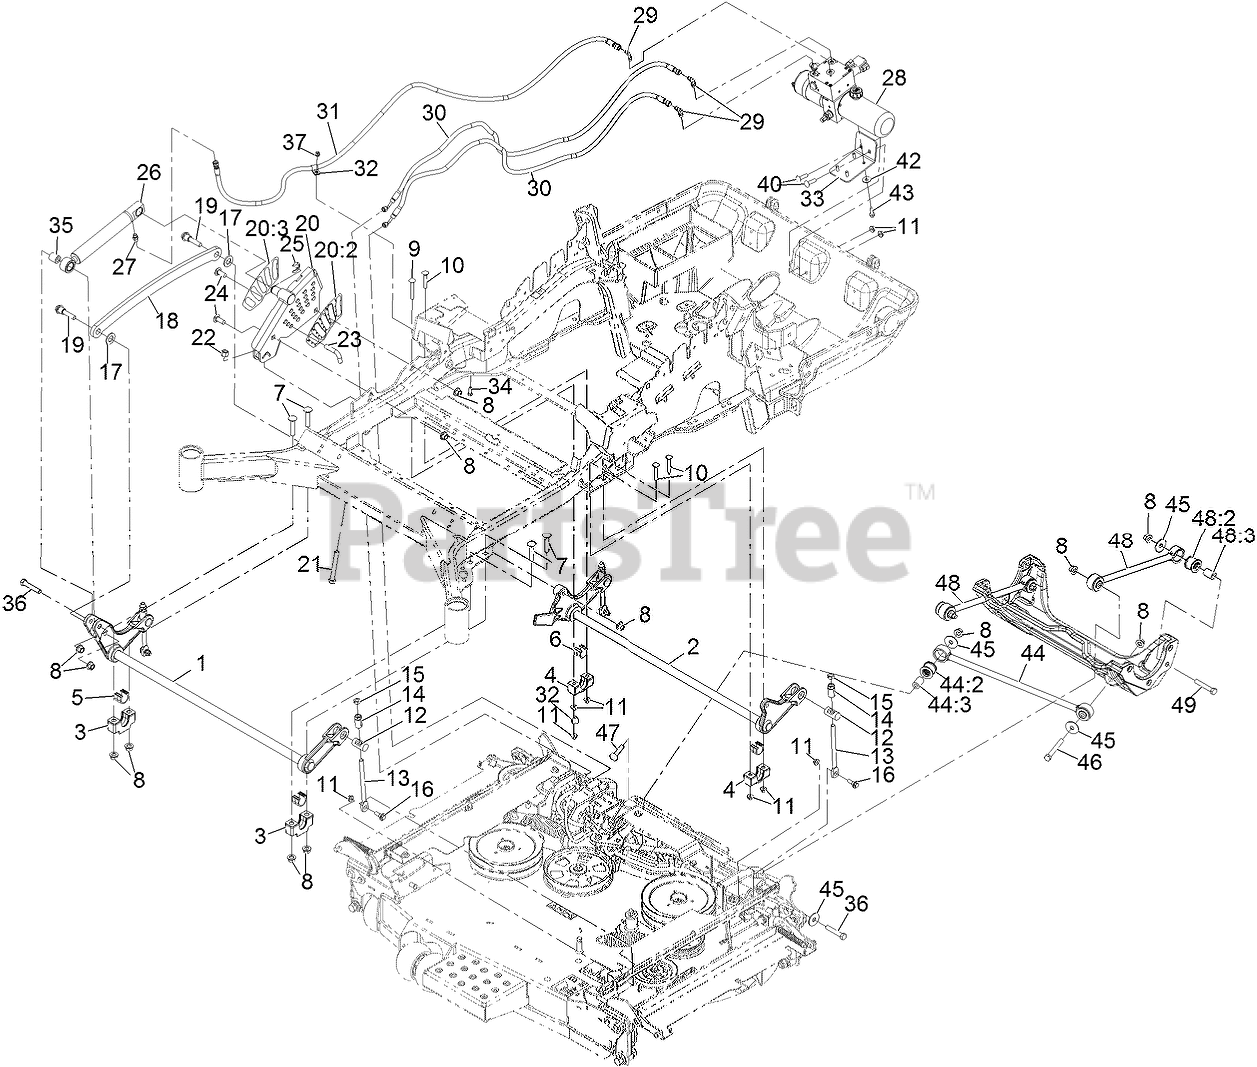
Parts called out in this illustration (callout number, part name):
1	DECKLIFT-FRONT
2	LIFT-DECK, REAR
3	SUPPORT-CROSS SHAFT, BEARING
4	SUPPORT-CROSS SHAFT, BEARING REAR
5	BEARING-CROSS SHAFT, FRON
6	BEARING-CROSS SHAFT, REAR
7	Bolt-Carriage 1/2-13 X 2 1/2 Spl Neck
8	Nut-Lock 1/2-13
9	SCREW-CARR
10	Bolt-Carriage 3/8-16 X 2 1/4
11	NUT-HF, NI
12	TRUNNION
13	LINK-ADJUSTER, DECK LIFT
14	ADJUSTER-LIFT, DECK
15	NUT-JAM
16	SCREW-SHOULDER, HHF
17	WASHER-FLAT
18	LINK-LIFT, DECK
19	SCREW-HHF, SHOULDER
20	HOC ASM
20:2	DECAL-HEIGHT OF CUT
20:3	DECAL-HEIGHT OF CUT, OUTER
21	BOLT-TAP
22	NUT-LOCK, NI
23	PIN-HOC
24	SCREW-CARR, SHORT NECK
25	RING-RETAINING
26	CYLINDER-LIFT
27	ADAPTER,STRAIGHT ORIFICED
28	Power Unit
29	ADAPTER,90 DEG
30	Hose-HYD, HP
31	Hose-HYD, HP
32	R-Clamp
33	Mount-Power Unit
34	SCREW-HH
35	SPACER-PIVOT
36	SCREW-HH
37	NUT-HF, NI
40	SCREW-CARR
42	WASHER-SPRING
43	SCREW-HHF
44	PANHARD ROD ASM
44:2	BUSHING-SUSPENSION, RUBBER
45	WASHER-THRUST
46	SCREW-HH
47	SCREW-CARR
48	ASM, DECK STRUT
48:2	BUSHING-RUBBER
49	SCREW-HH
